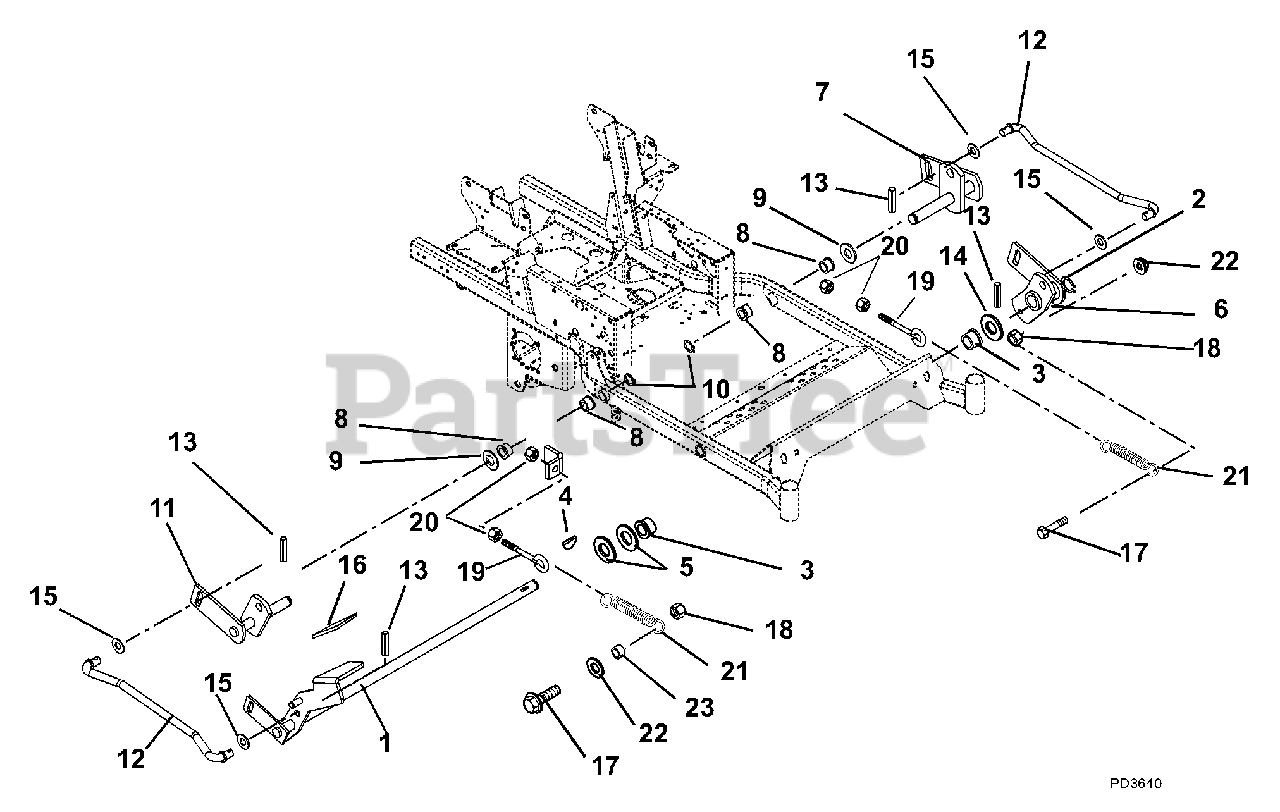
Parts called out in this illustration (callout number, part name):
1	Weldment, Lift Arm
2	Ring, Retaining External 1.00 x .078
3	Bushing, Flange
4	Key, Woodruff .25 x 1.00
5	Washer, Flat Steel 1.063 x 2.00 x .134
6	Lift Arm - Front
7	Weldment, Left Hand Rear Lift Arm (100)
8	Bushing, Flange Nylon .762 x 1.0 x .580 x 1.48
9	Washer, Hardened Steel .758 x 1.23 x .031
10	Ring, Retaining External .689 x .077
11	Weldment, Right Hand Rear Lift Arm (100)
12	Rod, Lift Assist
13	Pin, Roll .25 x 1.25 Stainless Steel
14	Washer, Hardened Thrust 1.00 x 1.55 x .03
15	Washer-Flat-Steel .630 x 1.250 x .062
16	Grip, Pedal
17	Bolt, Hex .38-16 x 1.00 Grade 5
18	Nut, Locking Jam Center .375-16
19	Eye-Bolt, .375-16 x 2.50
20	Nut, Hex Jam .375-16
21	Spring, Tension .162 x 1.25 x .25
22	Washer, Flat Steel .438 x 1.00 x .083
23	Spacer .377 x .624 x .235
